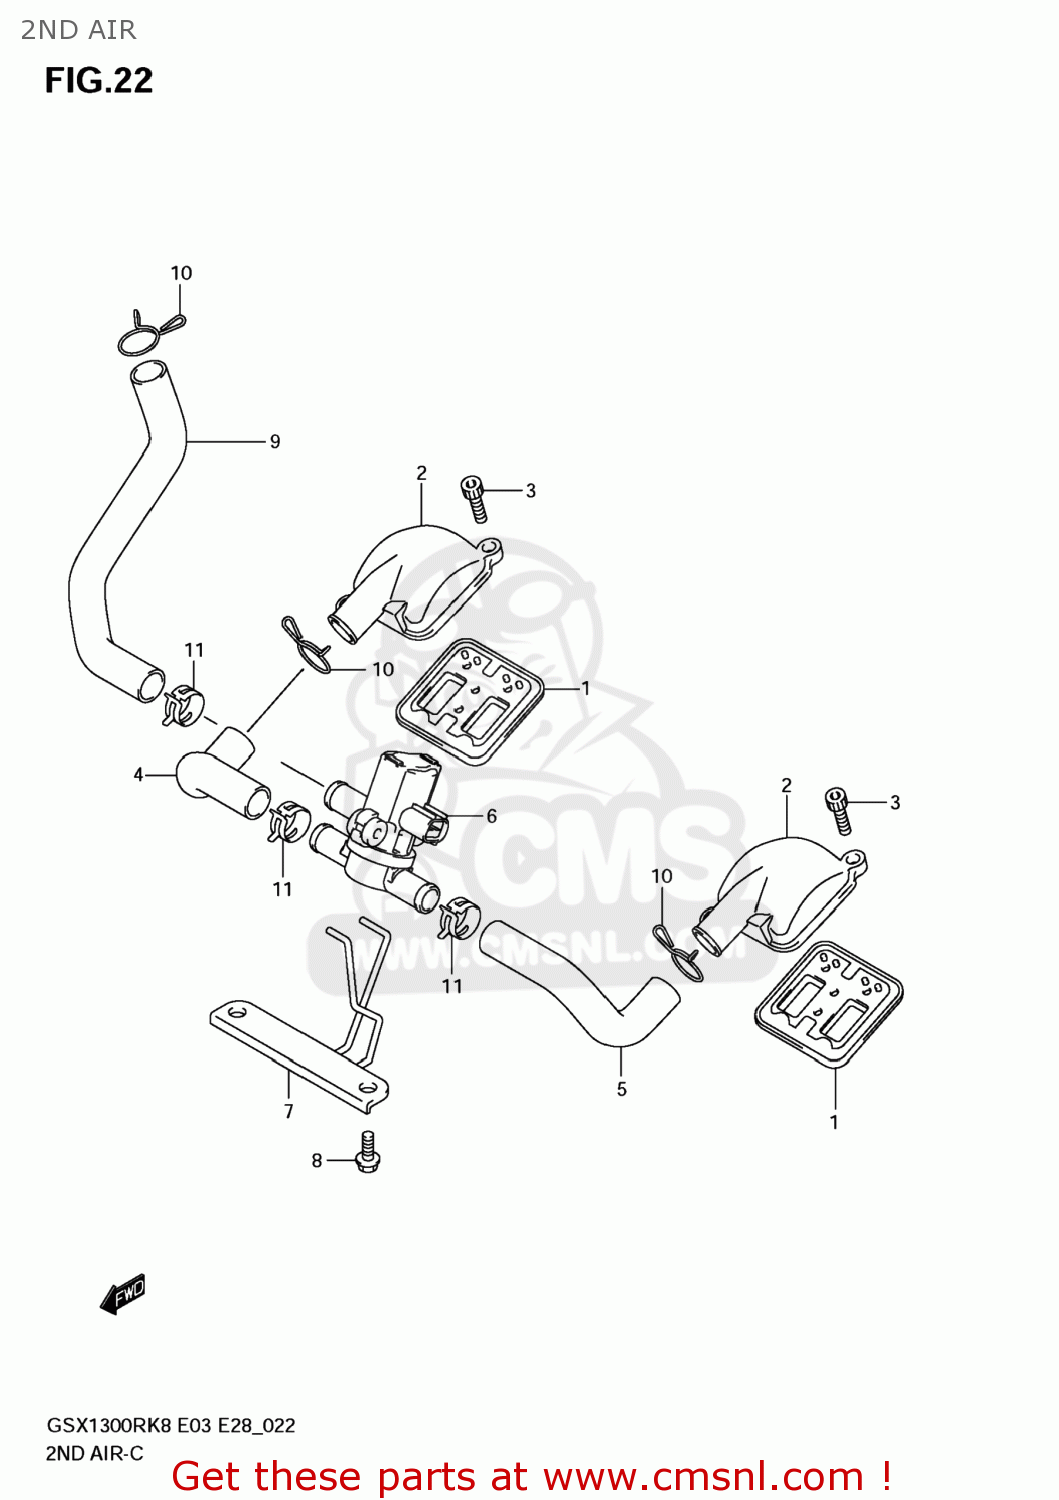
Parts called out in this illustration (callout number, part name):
1	VALVE ASSY,2ND AIR REED
2	COVER,2ND AIR REED VALVE
3	BOLT(6X16)
4	HOSE,2ND AIR VALVE,R
5	HOSE,2ND AIR VALVE,L
6	VALVE ASSY,AIR CUT
7	BRACKET,2ND AIR VALVE
8	BOLT(6X16)
9	HOSE,2ND AIR CLEANER
10	CLIP
11	CLIP
